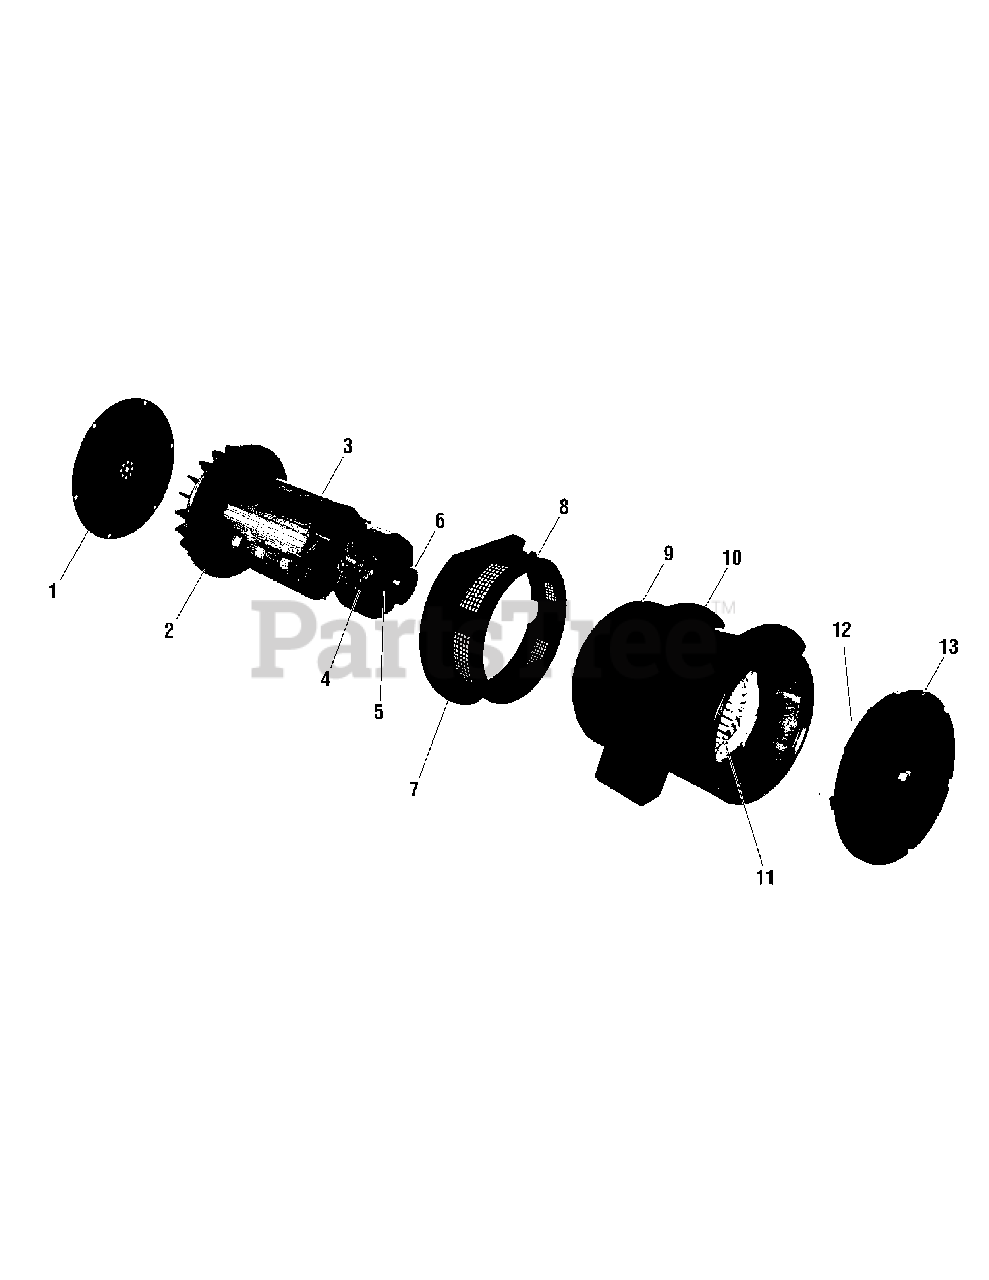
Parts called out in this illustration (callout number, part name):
1	DISC-COUPLING
2	FAN
3	ROTOR
5	RECTIFIER ASSEMBLY RING
7	HOUSING-BELL
8	SCREEN
9	HOUSING-GENERATOR
10	LIFTING EYE
11	STATOR
13	COVER
